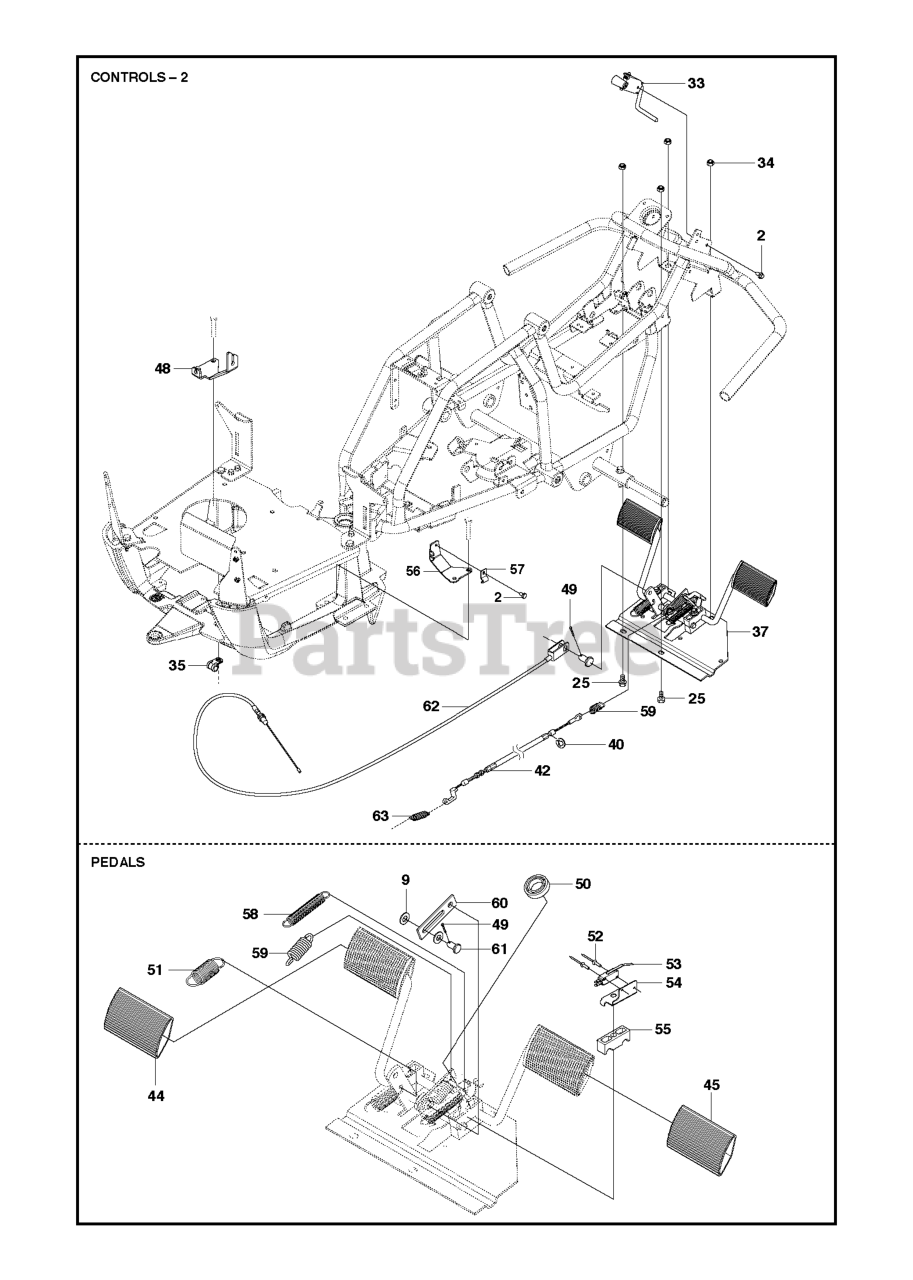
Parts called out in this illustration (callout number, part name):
9	WASHER BRB 8.4X17
44	PEDAL RUBBER, SF
45	PEDAL RUBBER
49	Cotter Pin
50	BALL BEARING 6002-2RS1
53	MICRO SWITCH
55	PEDAL SHAFT CLAMP
61	Clevis Pin
